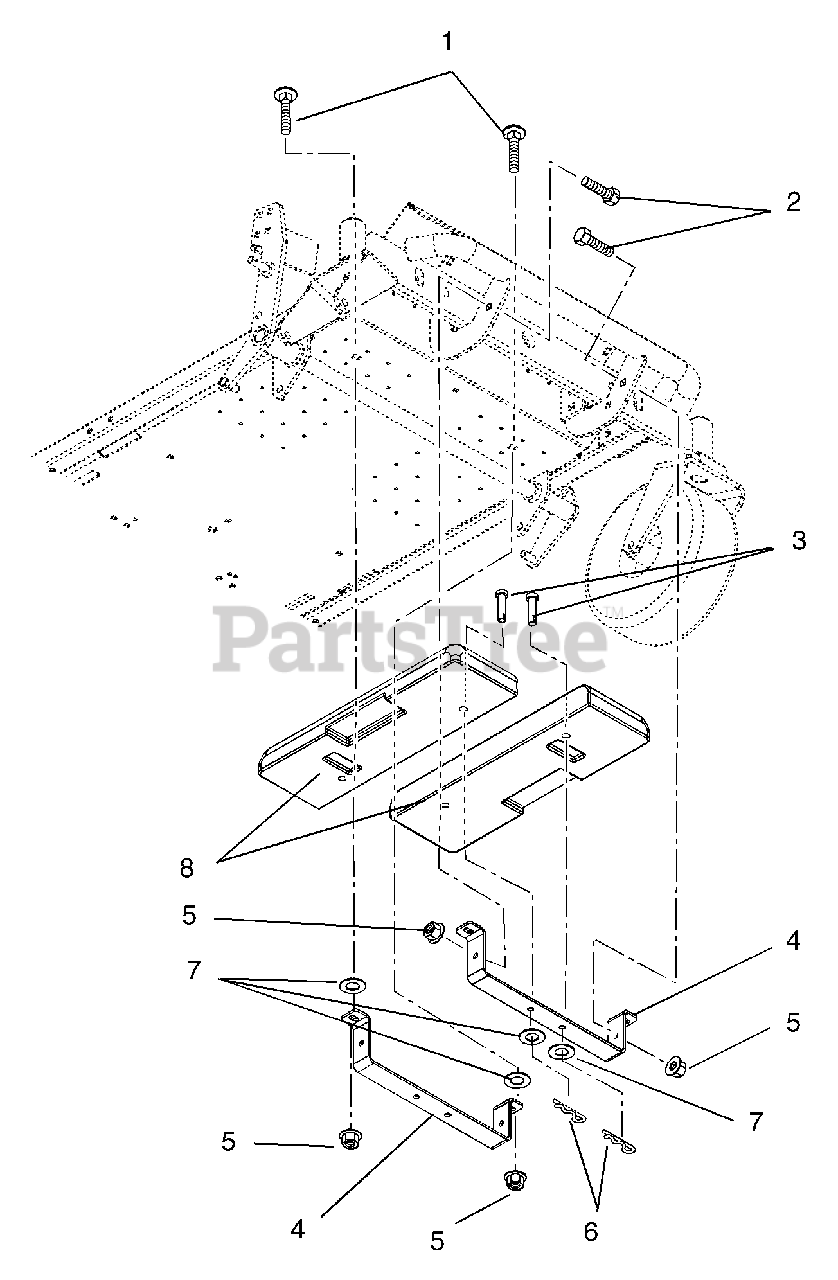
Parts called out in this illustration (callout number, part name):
1	@BLT-RDHDSQNK .38-16X1.00 G5YZ
2	@BLT-HEX .38-16X1.00 GR5 YWZC
3	PIN-CLEV .494X2.50 BRIGHT ZINC
4	BRACKET,WEIGHT
5	@NUT-LK-TOP-FLG .38-16 YWZC
6	PIN-HAIR-EXT .12X.31X2.37 YWZC
7	WSHR-FL-STL .515X1.625X.250 YZ
8	WEIGHT, CAST IRON
